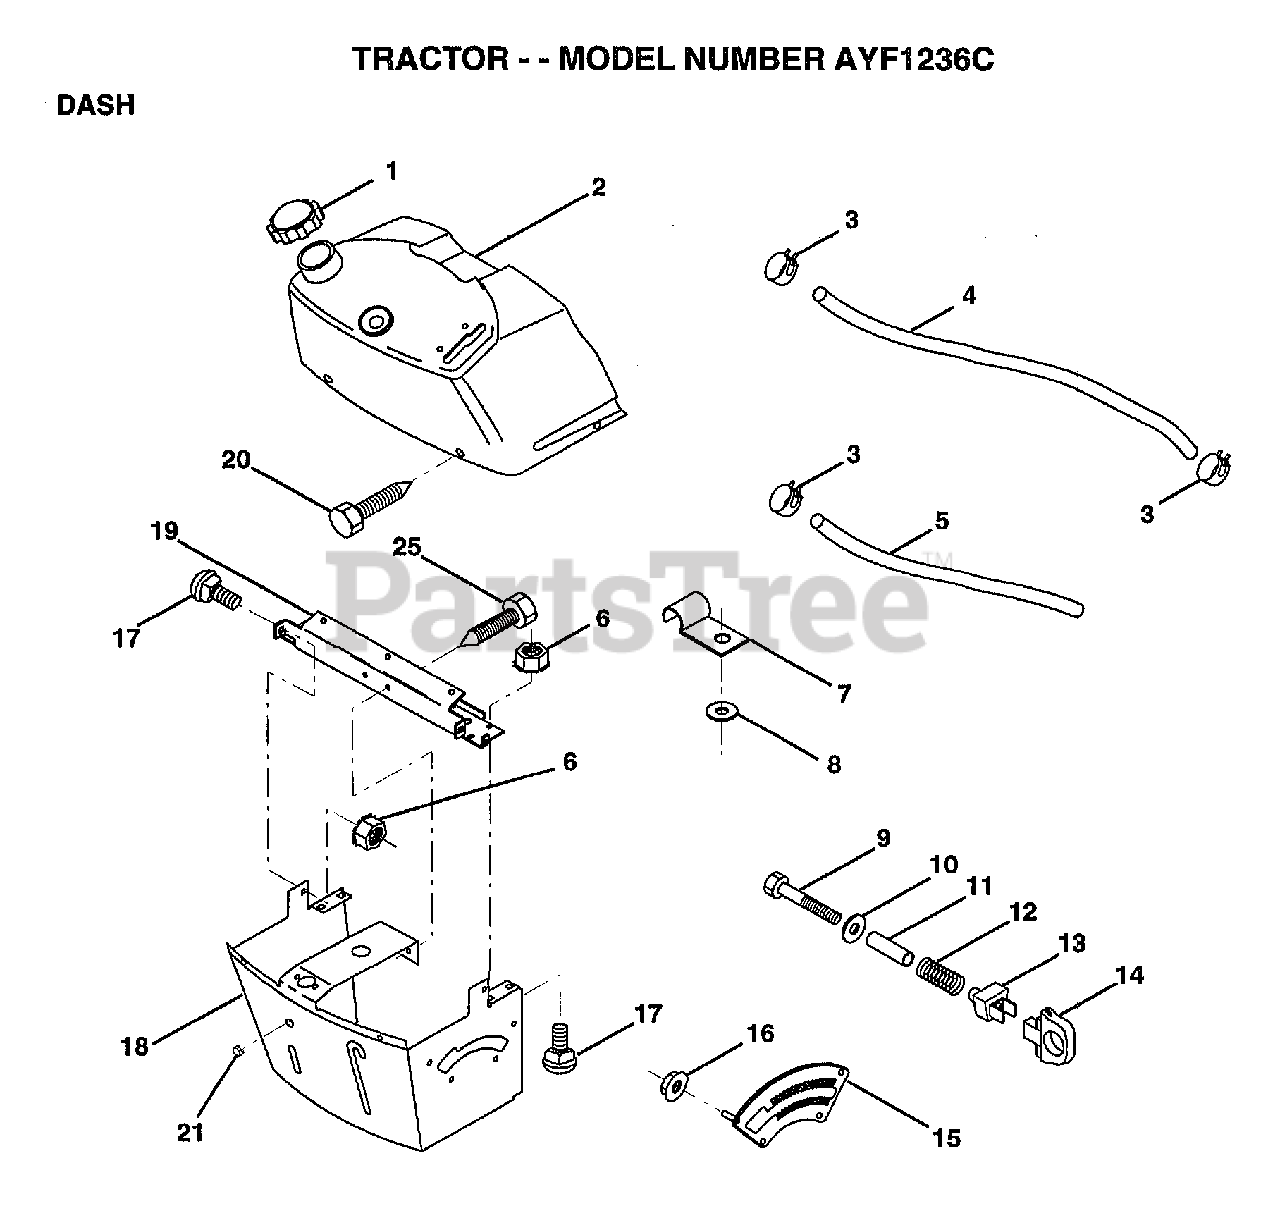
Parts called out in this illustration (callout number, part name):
1	CAP BLK FUEL LR
2	TANK.ASM.DASH.LR
3	HOSE CLAMP
5	FUEL LINE T
6	NUT HXKEP 1/4X20
7	CLIP T
8	WASHER PM
9	BOLT
11	SPACER SPLIT
12	SPRING M
13	"KNOB,HGT RETAINER"
14	KNOB
15	ADJUSTER QUAD
16	NUT
17	BOLT
18	SUPT ASSY DASH
19	CROSS BRACE
20	SCREW.1/4-20X1/2
21	PLUG DOME
25	SCREW LT
